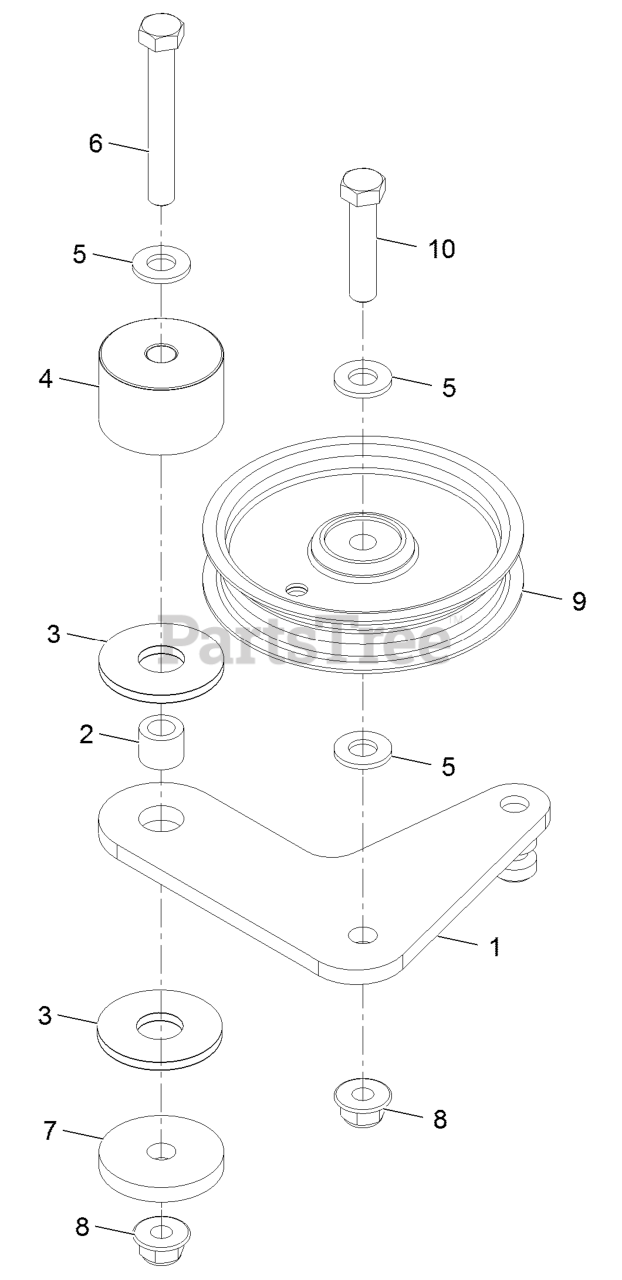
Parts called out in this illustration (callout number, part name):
1	PLATE-IDLER
2	BUSHING-LEVER, LIFT
3	WASHER-FRICTION, COMPOSIT
4	HUB, IDLER
5	WASHER-FLAT
6	SCREW-HH
7	WASHER-PLAIN
8	NUT-HF, NI
9	PULLEY-IDLER
10	SCREW-HH
